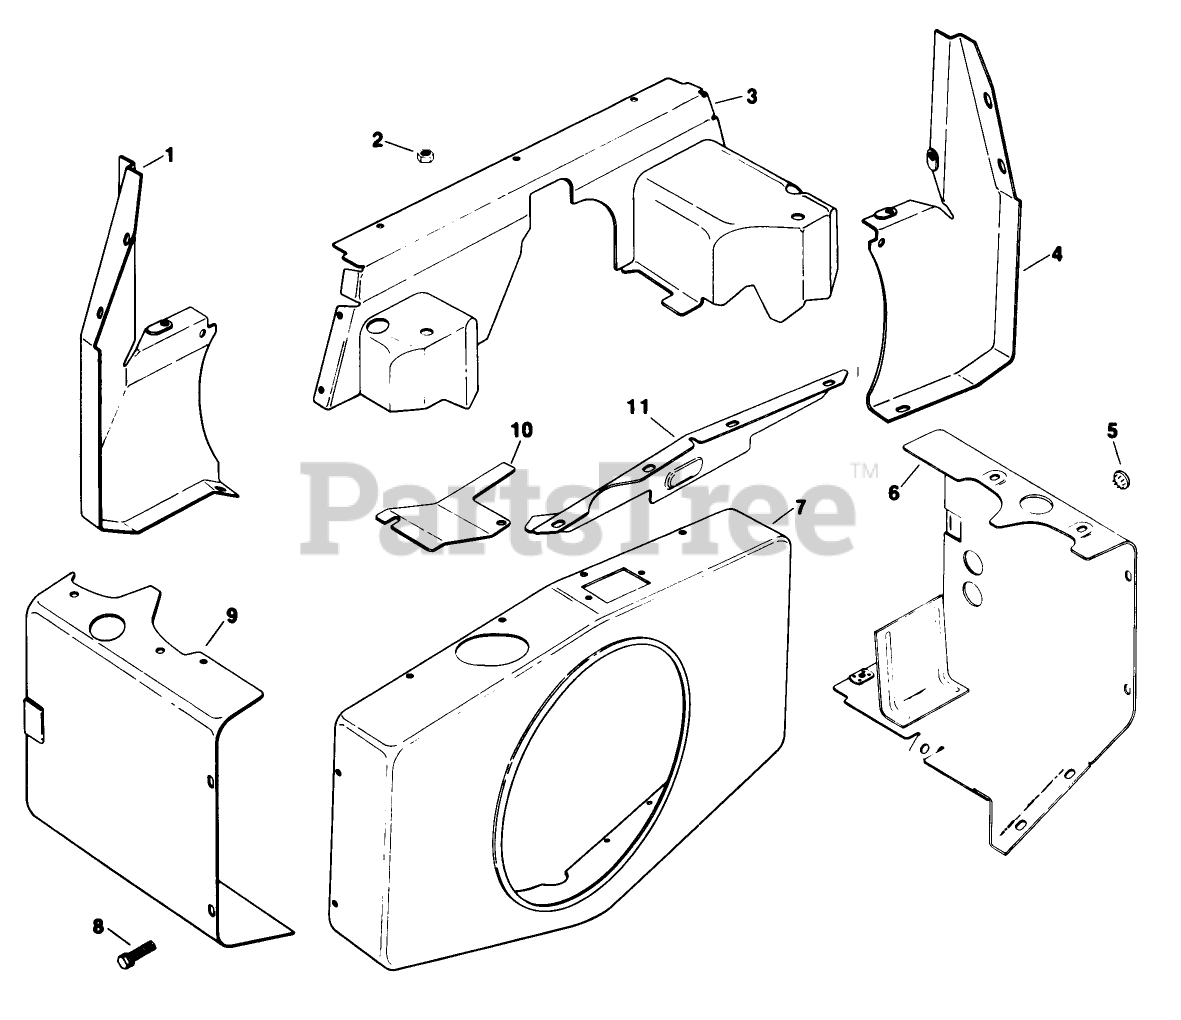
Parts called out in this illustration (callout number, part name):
1	Duct-#2 Side Air
3	Cover-Air Duct
4	#1 Side-Air Duct
5	Button-Plug
6	Baffle-#1 Cylinder Head
7	Housing Blower
8	Screw
9	Baffle-Cylinder Head
10	Baffle-Cylinder Head
11	Support-Upper Housing
